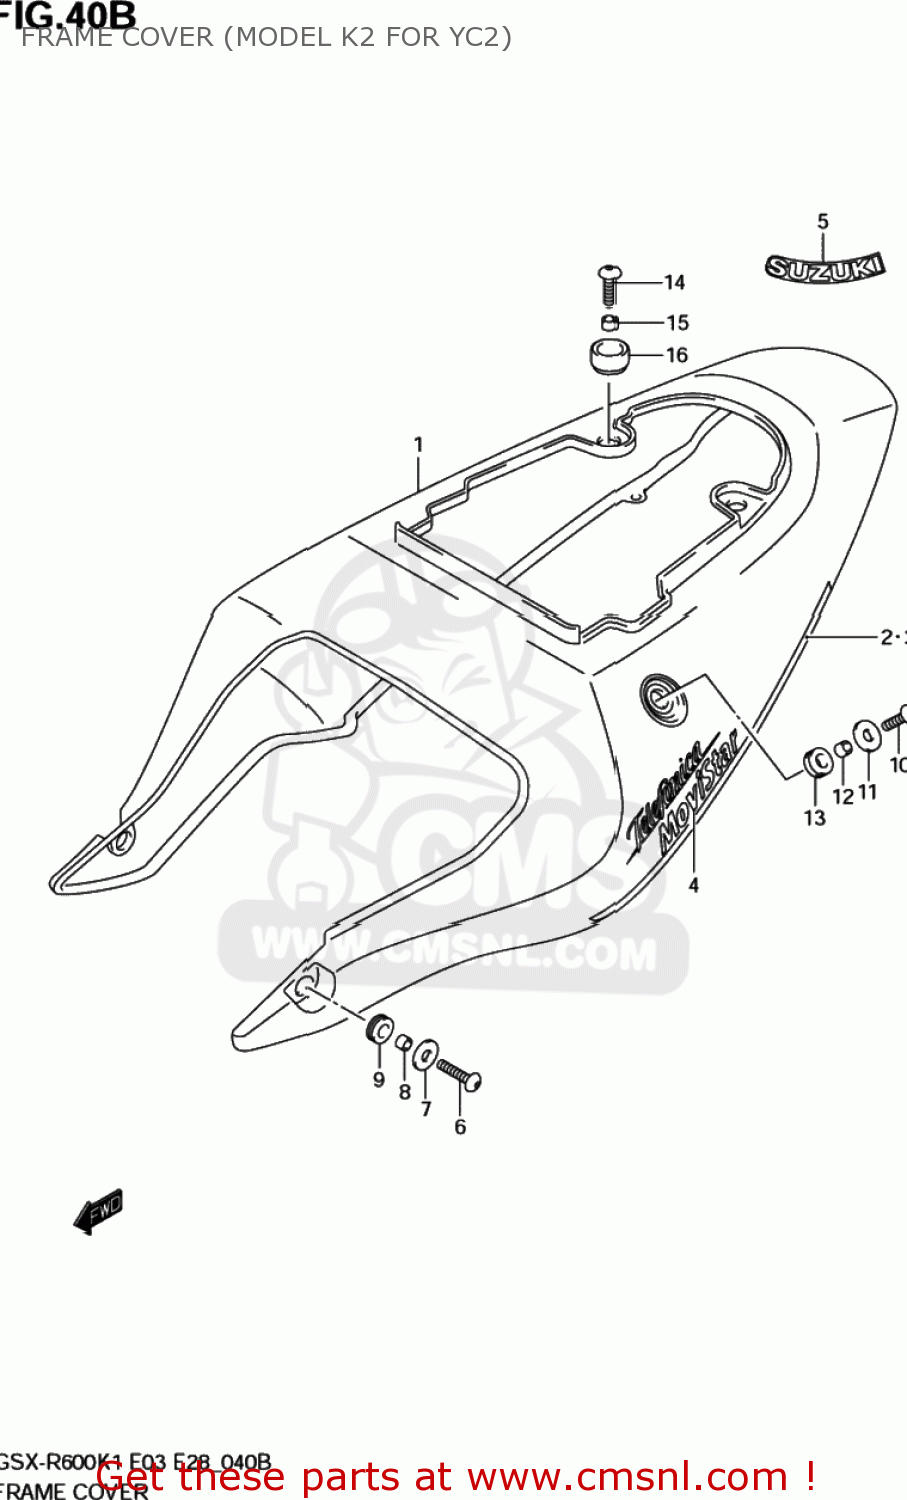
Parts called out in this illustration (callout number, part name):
1	COVER ASSY,FRAME(BLUE)
2	TAPE,FRAME COVER,R
3	TAPE,FRAME COVER,L
4	EMBLEM,MOVISTAR
5	EMBLEM(WHITE)
6	SCREW(6X30)
7	WASHER(6.5X20X2)
8	SPACER(6.5X10X7)
9	CUSHION,FRAME COVER FR
10	SCREW(6X25)
11	WASHER(6.5X20X2)
12	SPACER(6.5X10X7)
13	CUSHION,FRAME COVER SIDE
14	SCREW(6X25)
15	SPACER(6.5X10X9.4)
16	CUSHION
